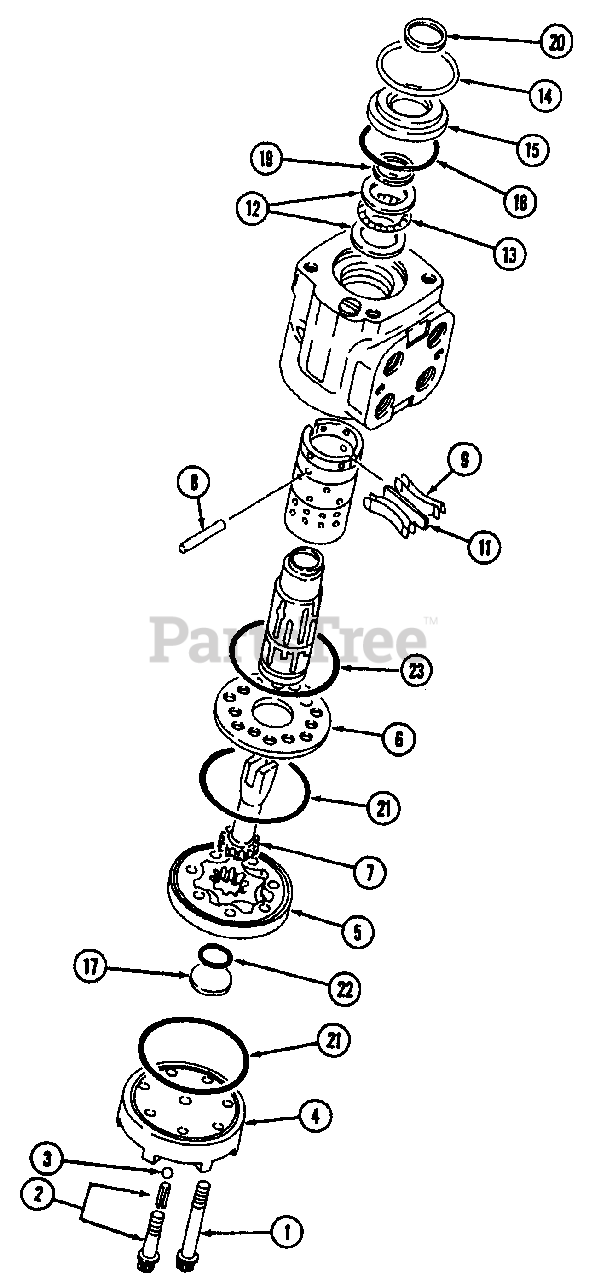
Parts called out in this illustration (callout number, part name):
2	Retainer, Screw Ass'y.
6	Plate, Spacer
9	Spring, Centering
13	Needle
18	O-Ring
19	Oil, Seal
20	Seal, Dust
23	O-Ring
